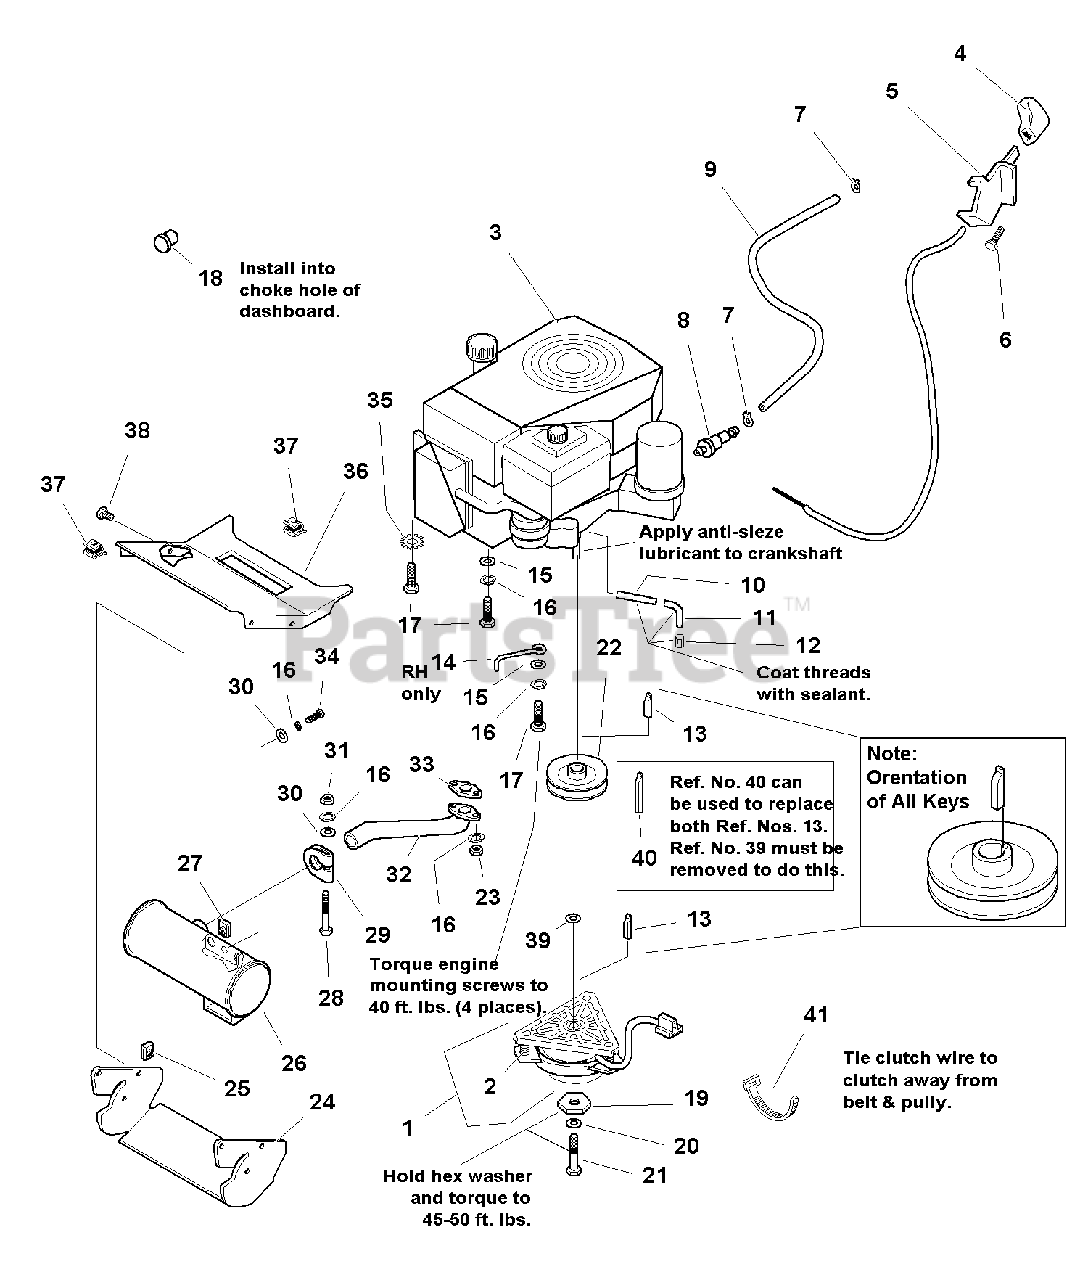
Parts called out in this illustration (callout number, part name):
1	CLUTCH, Electric Ogura
2	SPRING & NUT KIT
4	KNOB, Throttle Control
5	CONTROL, Throttle, Includes Cable
6	CAPSCREW, Hex Washer Head, Plastite, 1/4 x 1/2
7	CLAMP, Hose
8	FILTER, Fuel (1691732 only)
9	HOSE, Fuel, 45" long (Cut toHOSE, Fuel, Cut to 12th needed-See notes on page 28)
10	PIPE NIPPLE, 3/8 x 2
11	FITTING, Pipe Elbow Street
12	CAP, Hex, 3/8-18 NPT
13	KEY, Hi-Pro
14	STOP-BELT .213WIRE 3.12 ,0.75 BLK
15	WASHER, Flat, .34 ID x 1" OD
16	WASHER, Lock Helical Spring
17	CAPSCREW, Taptite, M8-1-1/4 x 30 mm
18	FASTENER, Panel
19	WASHER, Hex
20	LOCKWASHER, Spring, 7/16
21	CAPSCREW, Hex Head, 7/16-20 x 2-1/2
22	PULLEY ASSY. (14 HP Hydro Only)
23	NUT, Exhaust
24	DUCT, Muffler, Bottom
25	NUT, Speed Lug Type, 1/4-20
26	MUFFLER ASSEMBLY
27	NUT, Speed Lug Type, 5/16-18
28	BOLT, Carriage, Short Neck, 5/16-18 x 2-3/4, GR5
29	CLAMP, Muffler, 1.312 Dia.
30	WASHER, 5/16, .34 ID x 3/4 OD x .06 THK
31	NUT, Hex, 5/16-18 NC-2B
32	PIPE, Exhaust
33	GASKET, Exhaust
34	CAPSCREW, Hex Head, 5/16-18 x 1, G5
35	LOCKWASHER, External Tooth, 5/16
36	DUCT, Top, Muffler
37	CLIP, Wire, 1/8 Dia.
38	CAPSCREW, Hex Flange, Whiz Lock, 1/4-20 x 5/8
39	WASHER, 1, (As Required for All Front, As Required for K62 Rear)
40	KEY, Hi-Pro, 1/4 x 2
41	TIE, Self Locking, 3-5/8 LG
